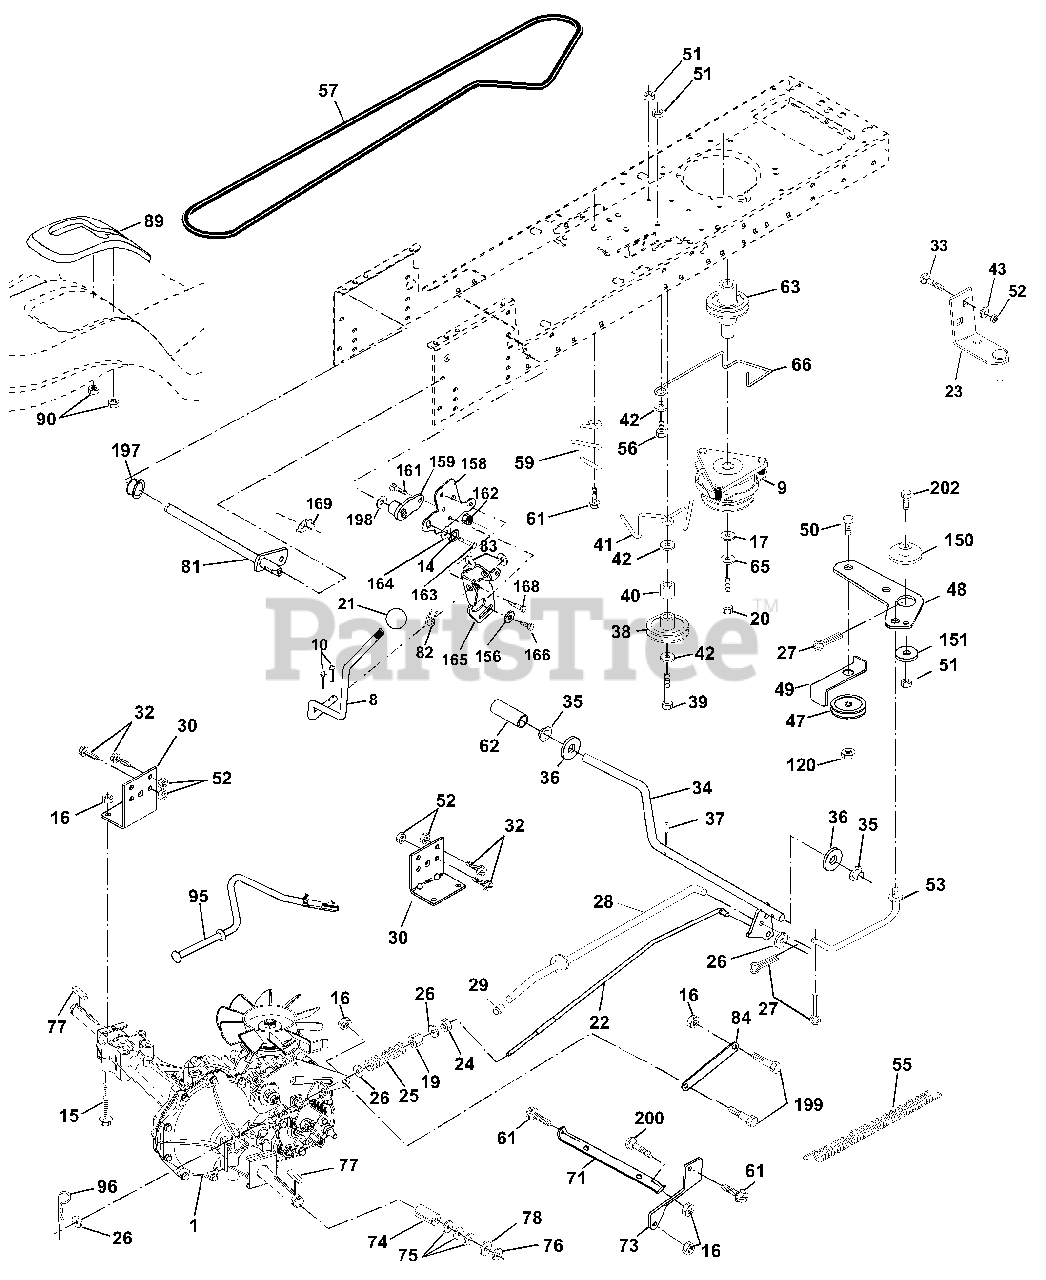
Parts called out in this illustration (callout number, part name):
8	Rod Shift Fender
9	Clutch Electric
10	Pin Cotter 1/8 x 1 CAD
14	Washer Lock Hvy Helical
15	Bolt Hex Flghd 5/16-18 Gr. 5
16	Nut Lock Hex W/Ins. 5/16-18 Unc
17	Washer 1-1/2 OD x 15/32 ID x .250
19	Nut Lock Hex W/Wsh 3/8-16 Unc
20	Bolt, Hex 7/16-20 x 4-1/4
21	Knob Deluxe
22	Rod, Brake Hydro
23	Bracket Asm. CVX
24	Locknut
25	Spring, Brake Rod
26	Washer
27	Pin Cotter 1/8 x 3/4 CAD.
28	Rod, Parking Brake
29	Cap, Parking Brake
30	Bracket, Transaxle
32	Bolt Hex Hd 5/16-18 Unc x 3/4
33	Bolt Carriage 5/16-18 UNC x 3/4
34	Shaft, Foot Pedal
35	Bearing, Nylon
36	Washer
37	Pin, Roll
38	Pulley, Idler, Flat
39	Bolt
40	Spacer Split
41	Keeper, Belt Idler Fool-Proof
42	Washer 13/32 x 13/16 x 12 Gauge
43	Washer 11/32 x 5/8 x 12 Ga.
47	Pulley, Idler, V-Groove
48	Bellcrank Clutch Grnd Drv Stl
49	Retainer, Belt
50	Bolt
51	Nut
52	Nut Crown Lock 5/16-18
53	Link, Clutch
55	Spring, Return, Clutch
56	Bolt
57	V-Belt, Ground Drive
59	Keeper, Center Span
61	Screw 3/8-16 x 3/4
62	Cover, Pedal
63	Pulley, Engine
65	Washer
66	Keeper Belt Engine Hydro
71	Strap Torque Lh Hydro
73	Strap Torque Rh Hydro
74	Spacer, Axle
75	Washer 25/32 x 1-1/4 x 16 Ga.
76	E-Ring
77	Key, Square
78	Washer 25/32 x 1-5/8 x 16 Ga.
81	Shaft Asm. Cross Hydro
82	Spring Torsion T/A
83	Washer 17/32 x 3/4 x 16 Ga.
84	Link Transaxle
89	Console, Shift
90	Nut Self-Thd Wsh-Hd 1/4
95	Control Asm. Bypass Hydro
96	Retainer Spring 1" Zinc/Cad
120	Nut Lock Flg. 3/8-16 Unc
144	Washer 11/32 x 5/8 x 16 Ga.
150	Bushing Bellcrank Grd Drive
151	Washer 13/32 x 2 x 10 Ga.
156	Washer Srrted 5/16ID x 1.125
158	Bracket Shift Mount
159	Hub Tapered Flange Shift Lt
161	Bolt Rdhd Sqnk 1/4-20 x 3/4 Gr. 5
162	Nut Crownlock 1/4-20 Unc
163	Bolt Hex Fin 1/4-20 Unc x 1 Gr. 5
164	Washer 5/8 x .281 x 10 Ga
165	Bracket Pivot Lever
166	Screw 5/16-18 x 5/8
168	Bolt Shoulder 5/16-18 x .561
169	Plate Fastening Lt\
197	Nyliner Snap-In 5/8" ID
198	Washer Nyliner 7/8 ID x .105
199	Bolt Shoulder 5/16-18 Unc
200	Bolt Rdhd Sqnk 5/16-18 UNC x 1
202	Bolt Carr Sh 3/8-16 x 1-1/2 Gr.5
